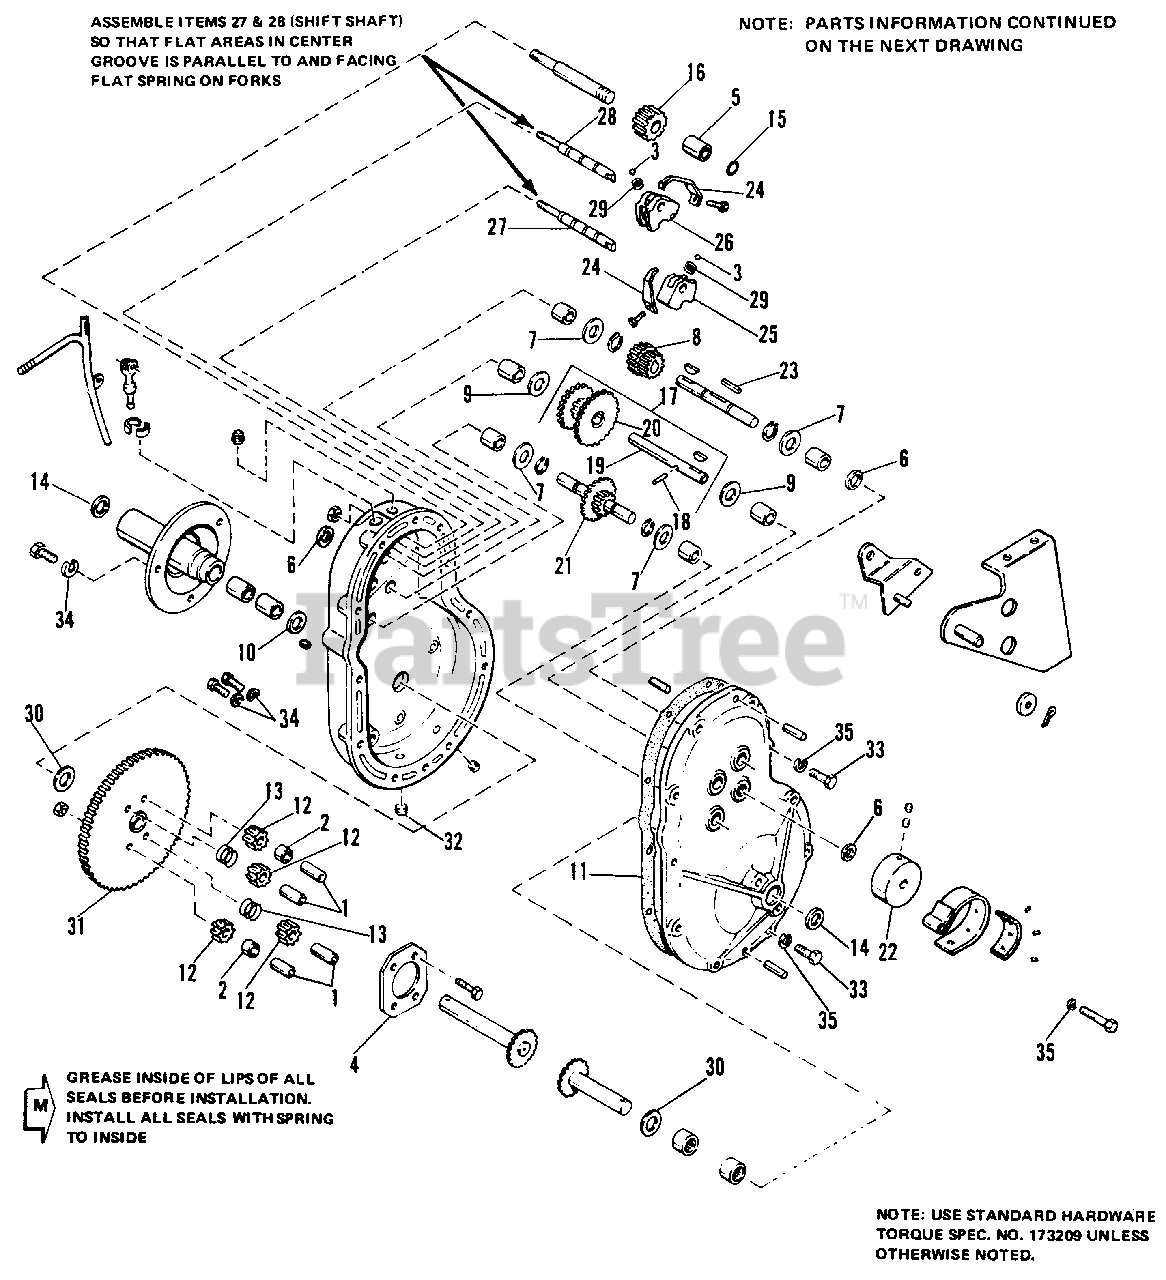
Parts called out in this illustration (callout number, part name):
2	SPACER, Differential
3	BALL, Shiftlock
4	PLATE, Differential
5	BEARING, Roller
8	PINION ASSEMBLY, HI & LO
11	GASKET, Case
12	PINION, Differential
16	PINION, Reverse
17	SHAFT & GEAR ASSEMBLY
18	PIN, Dowel
19	SHAFT, Brake
20	CLUSTER GEAR ASSEMBLY
21	GEAR & SHAFT ASSEMBLY
22	DRUM, Brake
25	SHIFT FORK, Reverse
26	SHIFT FORK, 1 & 2
27	SHAFT, Shift Reverse & Lo
28	SHAFT, Shift Hi & Lo
31	GEAR DRIVE ASSEMBLY
32	PLUG, Pipe, Sq. Hd., 3/8 Steel
33	CAPSCREW, Hex Hd., 5/16-18 N.C. x 1-1/4 GR. 5
34	LOCKWASHER, 3/8
35	LOCKWASHER, 5/16
